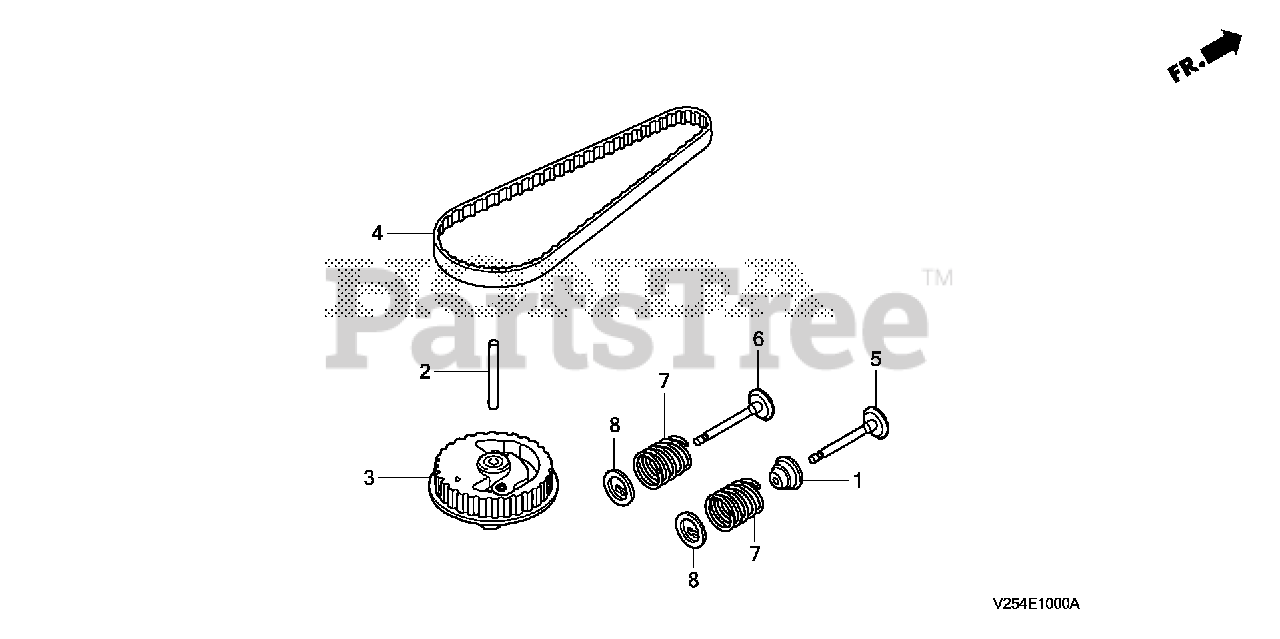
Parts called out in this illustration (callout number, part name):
1	SEAL, VALVE STEM
2	ROLLER (4X29.8)
3	PULLEY, CAMSHAFT
4	BELT, TIMING (71ZU5 G-310)
5	VALVE, IN.
5	VALVE, IN. (EI)
6	VALVE, EX. (EE)
7	SPRING, VALVE
8	RETAINER, VALVE SPRING
